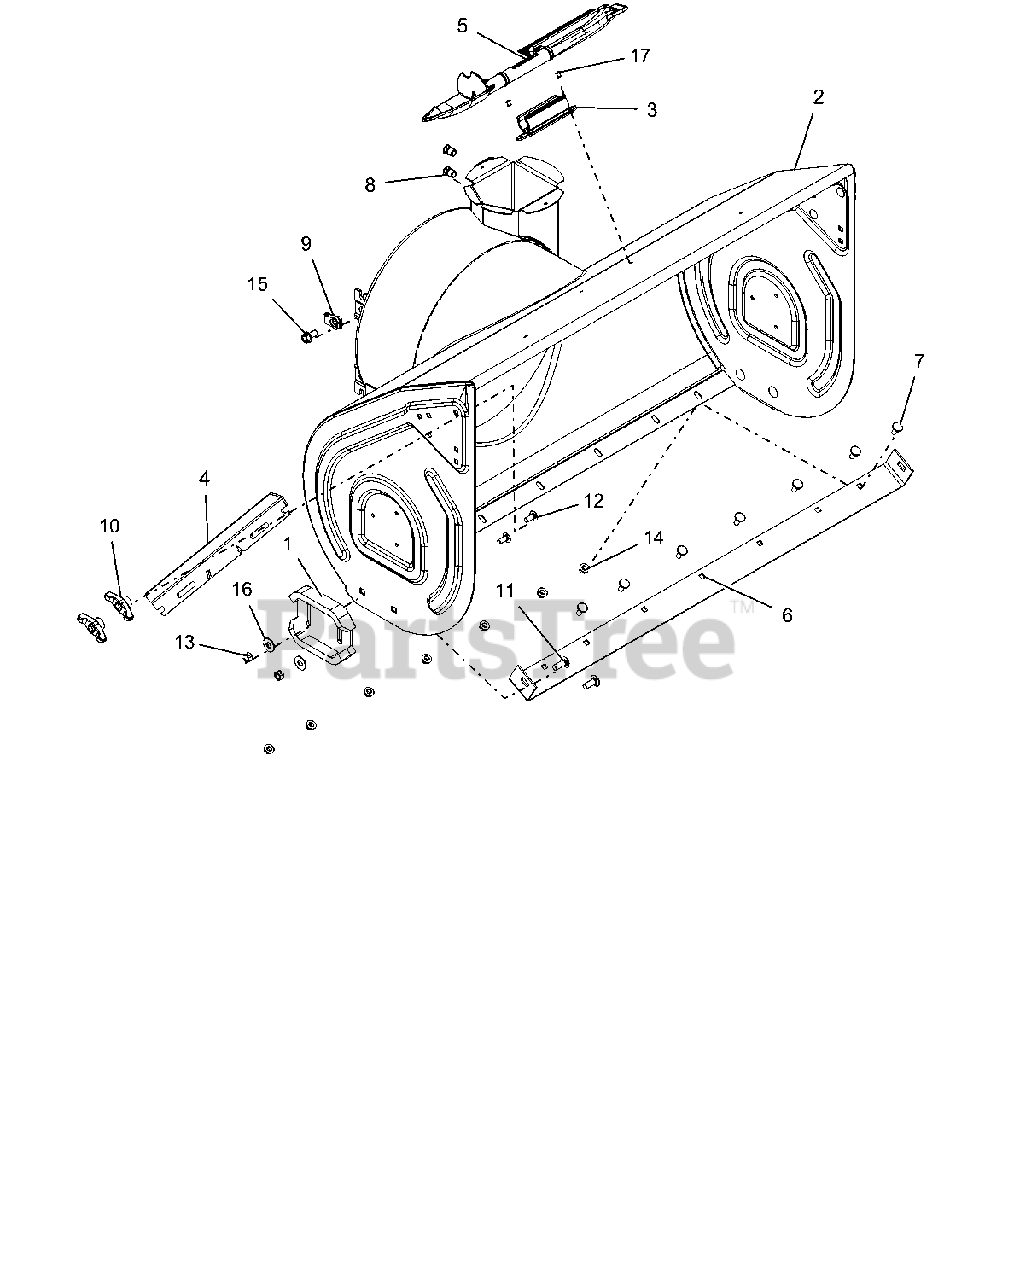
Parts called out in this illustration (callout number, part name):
1	RUNNER, SKID SHOE
2	BLOWER HOUSING W/DECAL 36"
3	MOUNT, SNOW CLEAN OUT
4	CUTTER, DRIFT
5	DEVICE, SNOW CLEAN OUT W/BRUSH
6	BLADE, SCRAPER-36"
7	BOLT, MODIFIED HEAD CARRIAGE
8	NUT, THREADED INSERT .38-16
9	NUT-RTNR .375-16X.37
10	KNOB,WING .31-18 UNC NYL/TALC
11	@BLT-RDHDSHSQNK.38-16X1.0 G5YZ
12	@BLT-RHDSSQNK .31-18X.75 G5YZ
13	@NUT-LK-CTR .38-16 YWZC
14	@NUT-LK-TOP-FLG .31-18 YWZC
15	BLT-SERHFWH .38-16X.75 YWZC
16	@WSHR-FL-STL.438X1.00X.083 YWZ
17	RVT-POP .187 YZ
